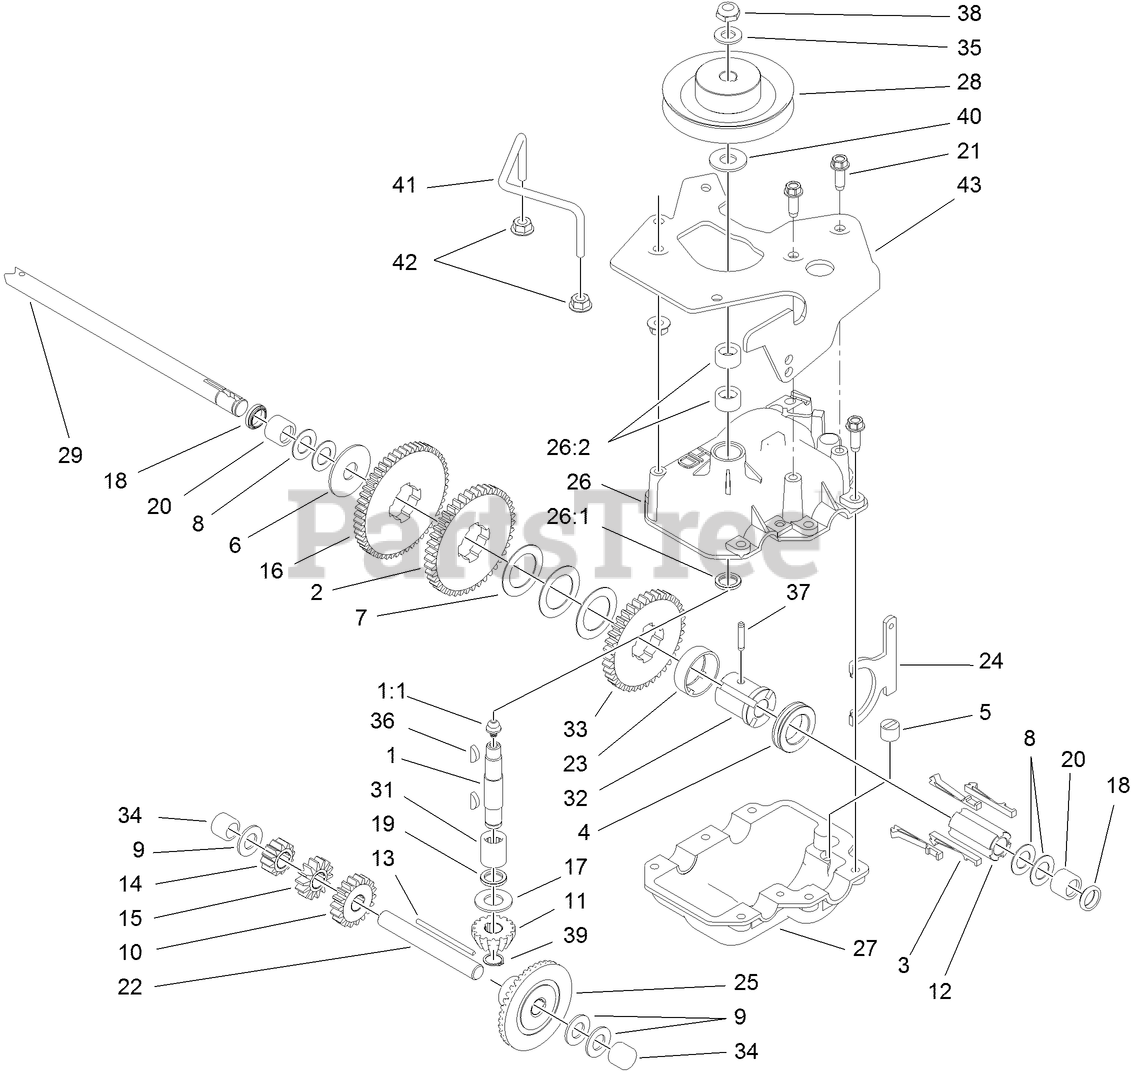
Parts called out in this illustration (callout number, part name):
1	INPUT SHAFT ASM
1:1	FITTING-GREASE, ZERK
2	GEAR-42T
3	KEY-SHIFT
4	COLLAR-SHIFT
5	BUSHING-YOKE
6	WASHER
7	WASHER
8	WASHER-PLAIN
9	WASHER-THRUST
10	GEAR-18T
11	PINION-BEVEL
12	SLEEVE
14	GEAR-12T
15	GEAR-14T
17	WASHER-THRUST
18	SEAL-OIL
20	BEARING-CAGED NEEDLE ROLLER
21	SCREW-HWHTF
22	SHAFT-INTERMEDIATE
23	RETAINER-KEY
24	YOKE-SHIFT
25	GEAR-BEVEL
26	UPPER GEARCASE ASM
26:2	BEARING-NEEDLE
27	GEARCASE-LOWER
28	SHEAVE
29	SHAFT-AXLE
31	BEARING-ROLLER, CAGED
32	SLEEVE-4 DOG
33	GEAR-38T
34	BEARING-NEEDLE, CLOSED
35	WASHER-FLAT
36	KEY-WOODRUFF
37	PIN-GROOVE
38	NUT-HEX
39	RING-RETAINING
40	WASHER
41	GUIDE-BELT
42	NUT-HF
43	BRACKET-GUIDE, BELT
